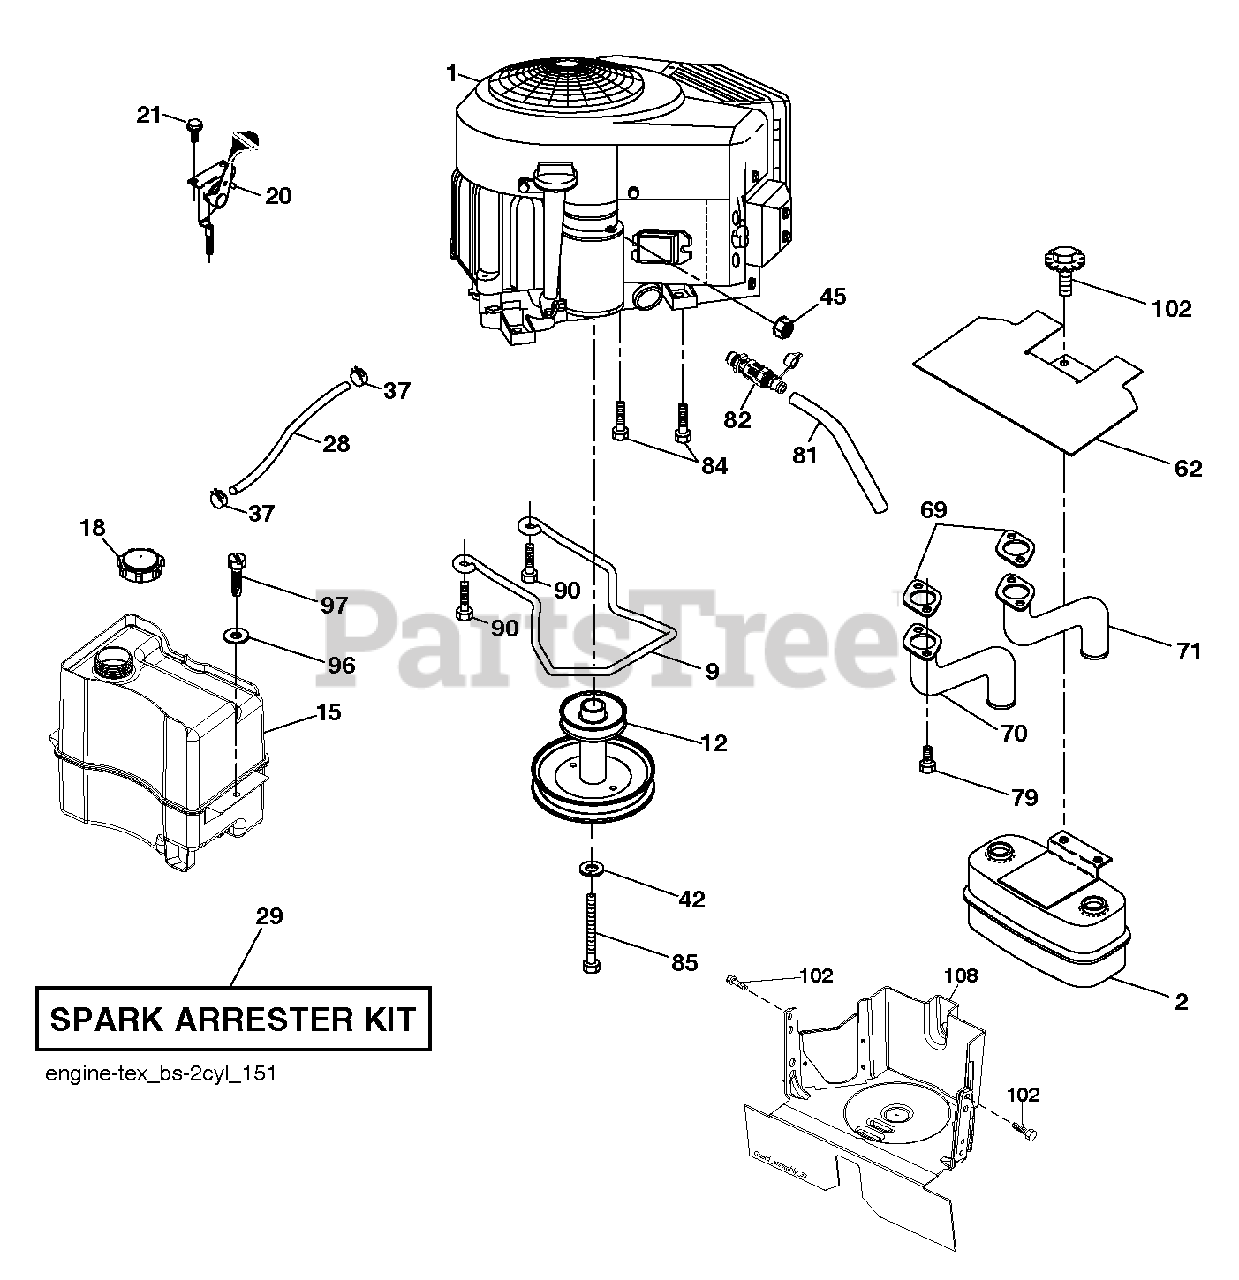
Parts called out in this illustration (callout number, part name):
2	MUFFLER.ASM.TWN.EXTNDED.DFLCTR
9	KEEPER.BELT.ENG.4.25"2.BLT.431
12	ENGINE.PULLEY
15	TANK.ASSEMBL.2.5GAL.NON-EPA
18	CAP ASM.FUEL.2.25"FR.
20	THROTTLE.COBRA.38"READSTART.BK
21	SCREW.#10 X 0.750.BOS
28	LINE.FUEL.20
29	KIT.SPARK ARRESTOR 794945 B&S
37	HOSE CLAMP
42	LOCKWASHER
45	NUT
62	SHIELD.HEAT.MUFFLER
69	GASKET.MUFFLER
70	EXHAUST.TUBE.LH.BS/TWIN
71	EXHAUST.TUBE.RH.B&S.TWIN.INTEK
79	SCREW.SOCKET.HEAD.5/16-18
81	TUBE, DRAIN OIL ASM.
82	VALUE.OIL.DRAIN
84	SCREW.3/8-16
85	BOLT.HEX.7/16-20X4.GR5.1.5BLUE
90	SCREW 3/8-16X1
96	WASHER
97	SCREW HEXWSHR 1/4-20X3/4
102	SCREW
108	COVER PULLEY
